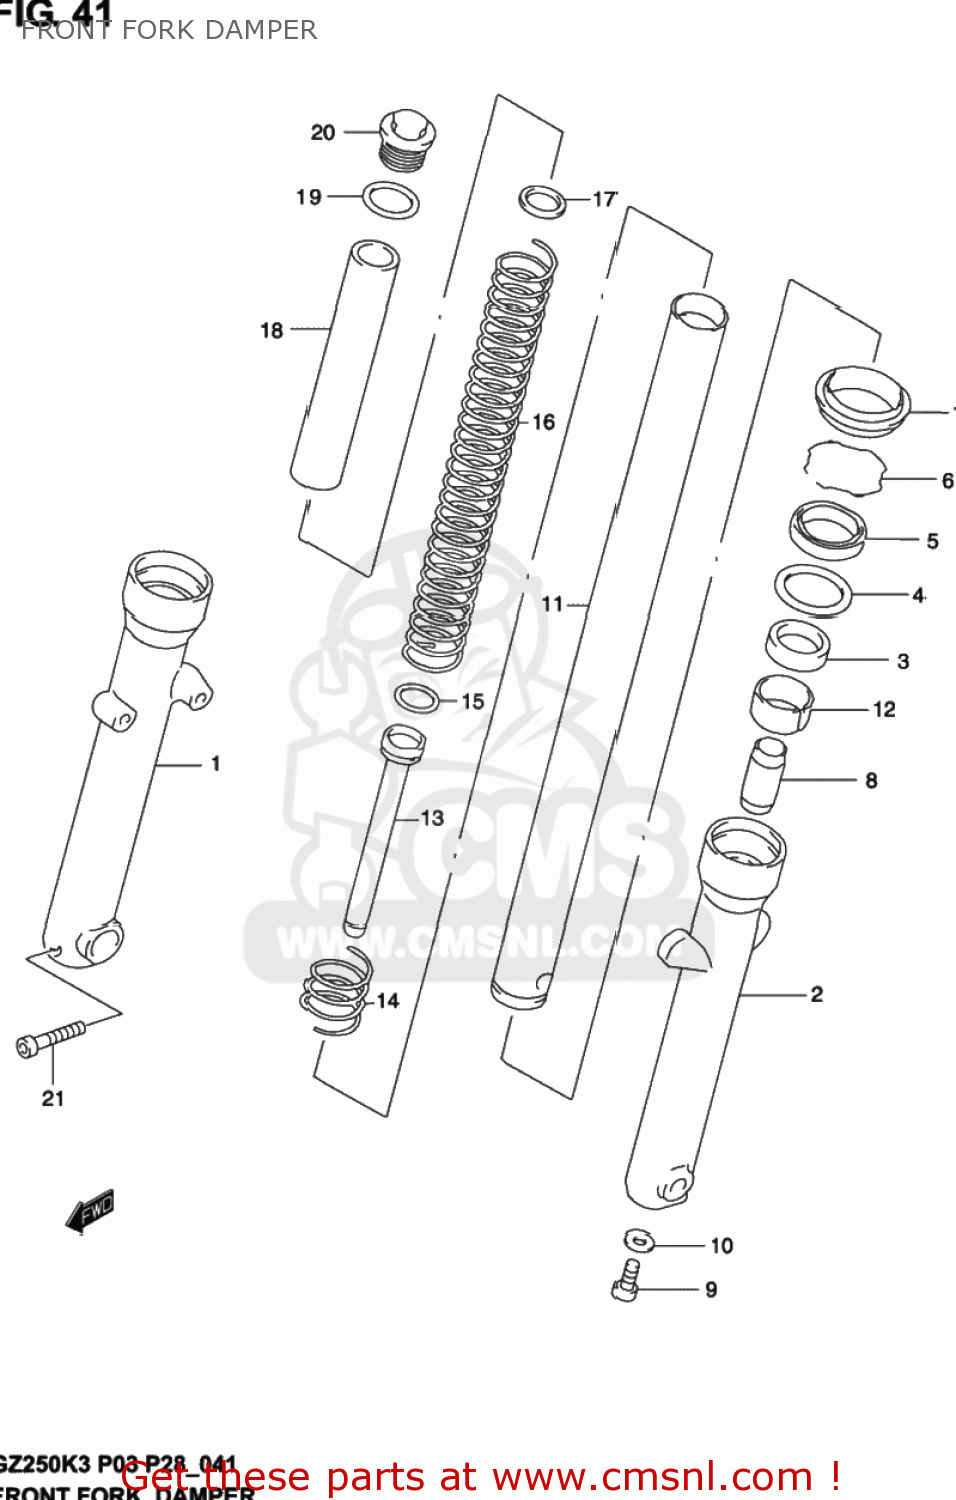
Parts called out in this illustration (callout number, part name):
1	TUBE OUTER R
2	TUBE, OUTER LH
3	BUSHING,GUIDE
4	SPACER, SEAL
5	OIL SEAL,FRONT FORK
6	RING, STOPPER
7	SEAL,DUST
8	PIECE,OIL LOCK
9	BOLT,CENTER (8X18)
10	GASKET (NAS)
11	INNER TUBE
12	BUSH,SLIDE
13	PIPE,SEAT
14	SPRING,REBOUND
15	RING,PISTON
16	SPRING,FR
17	JOINT,SPRING
18	SPACER,SPRING
19	O RING
20	BOLT,FR FORK
21	BOLT
